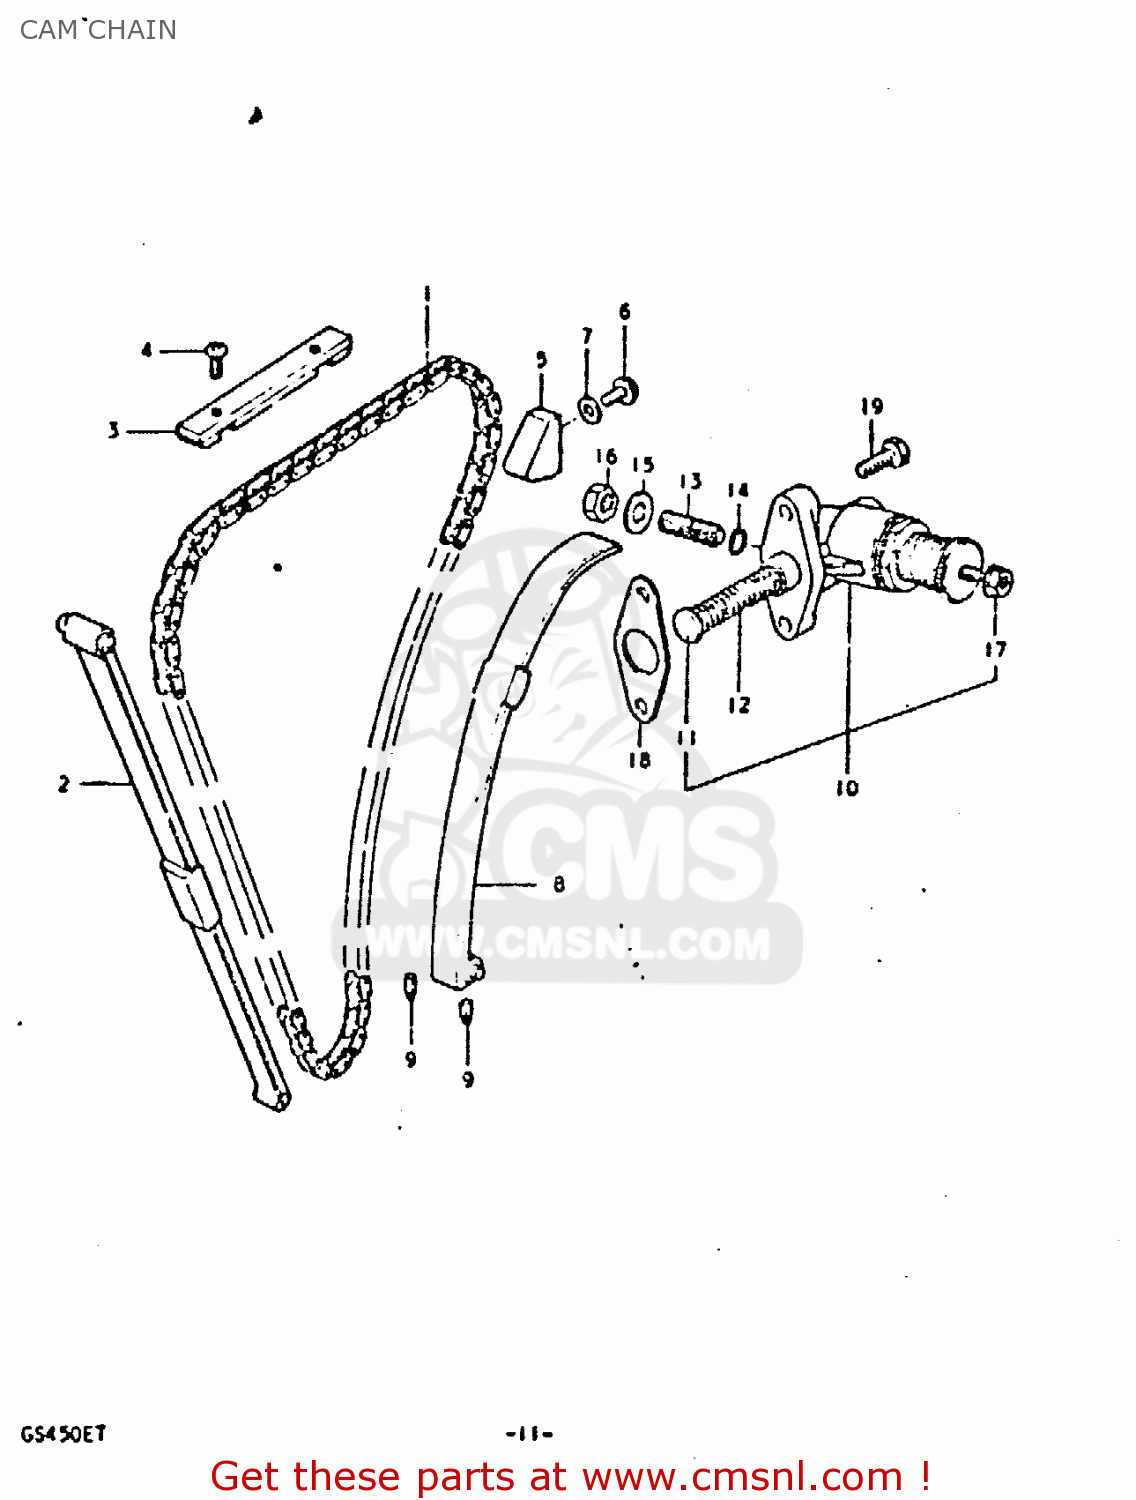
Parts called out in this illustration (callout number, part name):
1	CHAIN,CAMSHAFT DRIVE(120L)
2	GUIDE,CAM CHAIN NO.1
3	GUIDE,CAM CHAIN NO.3
4	SCREW
5	GUIDE,CAM CHAIN
6	BOLT
7	GASKET (NAS)
8	TENSIONER,CAM CHAIN
9	CUSHION,CAM CHAIN TENSIONER
10	ADJUSTER ASSEMBLY,TENSIONER
11	ROD,PUSH
12	SPRING
13	SCREW
14	O-RING
15	WASHER
16	NUT
17	NUT
18	GASKET,TENSIONER ADJUSTER (MCA)
19	SCREW (6X25)
